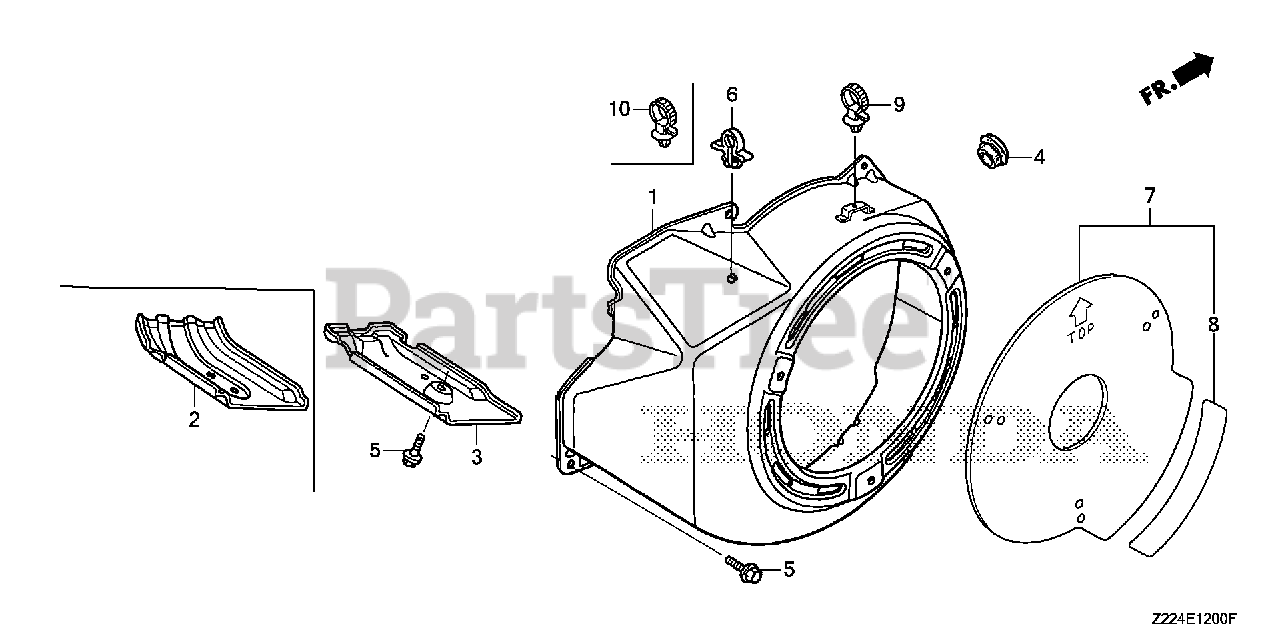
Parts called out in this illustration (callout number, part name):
1	COVER, FAN *NH1* (BLACK)
4	GROMMET, DRAIN HOLE
5	BOLT, FLANGE (6X12) (CT200)
6	CLIP, WIRE HARNESS (6MM) (WHITE)
9	BAND, HARNESS (98MM) (NATURAL)
